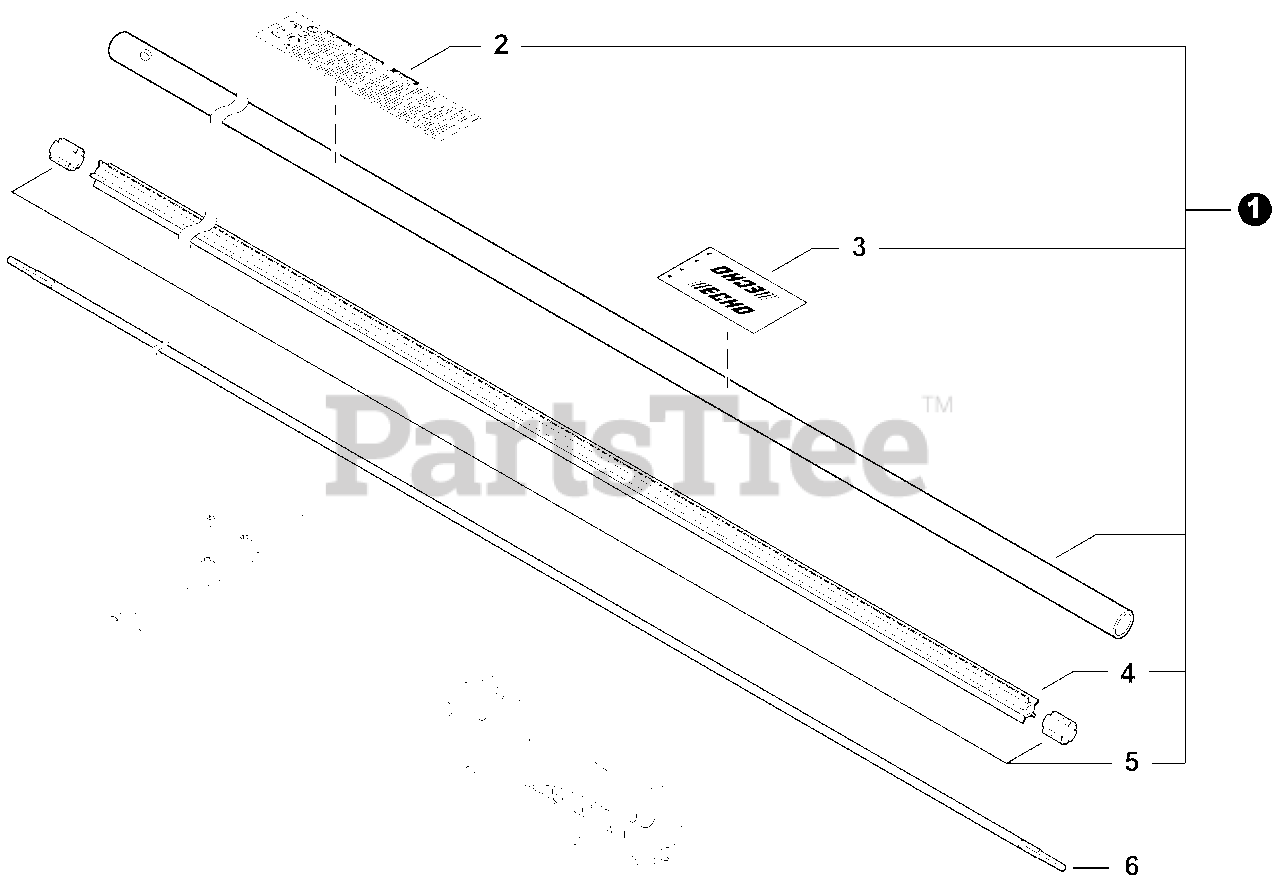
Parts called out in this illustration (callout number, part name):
1	MAIN PIPE ASSY
2	LABEL, CAUTION
3	LABEL, HANDLE LOCATION
4	LINER, FLEXIBLE 21.6×1420
6	DRIVESHAFT - FLEXIBLE
